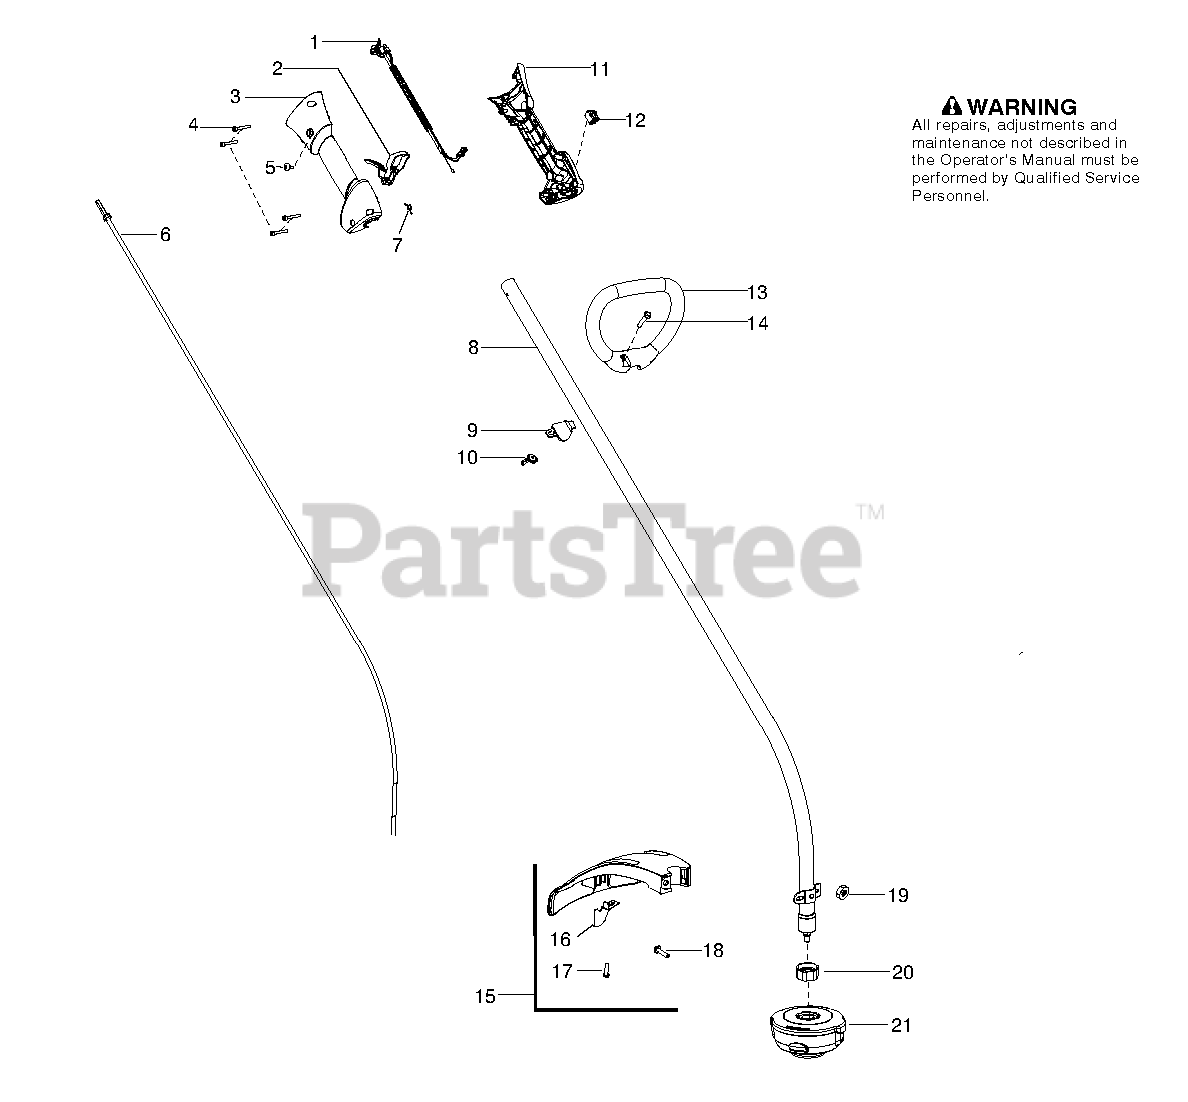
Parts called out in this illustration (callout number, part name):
1	ASSY CABLE / WIRE HARNESS
2	TRIGGER
3	HOUSING THROTTLE RH
4	SCREW M4 X 1.75 PT 16MM
5	SCREW-10-16 X 1/2, TYPE 2
6	FLEX SHAFT "C UNIT"
7	SPRING TRIGGER
8	KIT DRIVESHAFT
9	CLAMP ASSIST HANDLE
10	WINGNUT, TYPE 2
11	HOUSING THROTTLE LH
12	SWITCH
13	HANDLE ASSIST
14	BOLT, TYPE 2
15	KIT SHIELD
16	KIT - LIMITER - LINE
18	BOLT, TYPE 2
19	WINGNUT, TYPE 2
21	T25 TRIM HEAD RH
